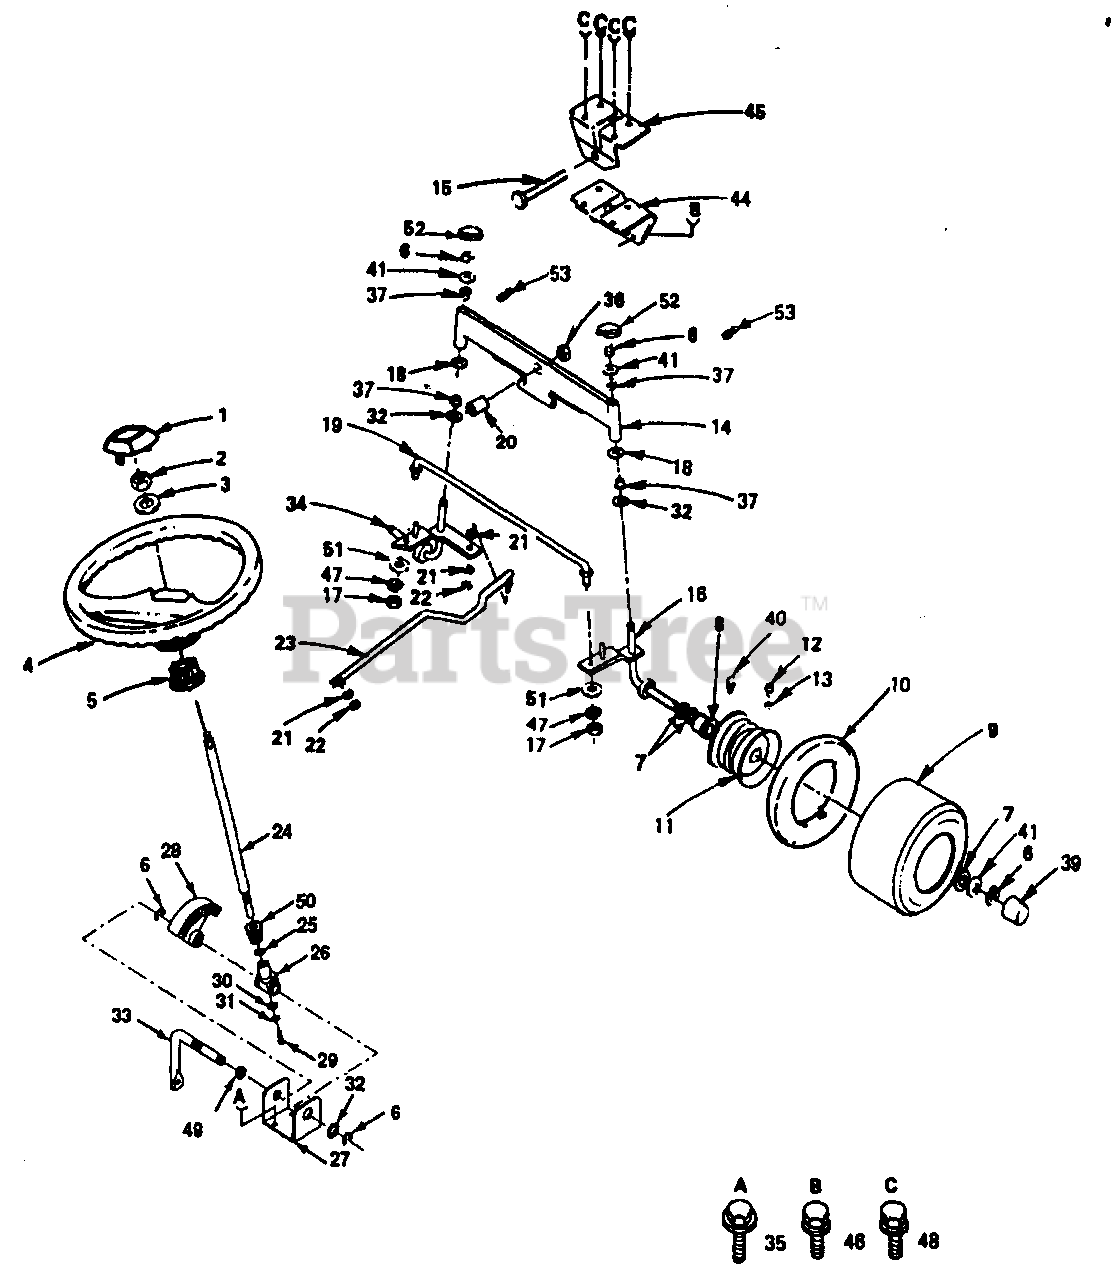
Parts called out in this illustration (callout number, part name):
1	Cap, Steering Wheel
2	Nut, Hex, Toplock Jam 1/2-20
3	Washer 17/32 x 2-1/4 x .160
4	Steering Wheel
5	Adapter, Steering Wheel
7	Washer 25/32 x 1-1/4 x 16 Gauge
8	Wheel Bearings, Front
9	Tire
11	Rim Assembly, Front
14	Axle Assembly, Front
15	Bolt, Hex 5/8-11 x 3-3/4
16	Spindle, Assembly, R.H.
17	Nut, Hex 5/16-24
18	Washer 27/32 x 1-1/4 x 16 Gauge
19	Rod, Tie
20	Spacer, Bearing
21	Washer, Lock 3/8
22	Nut, Hex 3/8-24
23	Link, Drag
24	Shaft Assembly, Steering
26	Support,Shaft
27	Bracket, Steering
28	Gear, Sector
29	Screw, Socket, Hex 1/4 - 20 x 5/8
30	Washer, Shim 1/4 x 5/8 x .062
31	Washer, Lock 1/4
32	Bearing, Thrust
33	Shaft, Pitman
34	Spindle Assembly, L.H.
35	Screw, Hex Washer Head, Thread Forming 3/8-16 x 3/4 Type TT
36	Locknut, Flange 5/8--11
37	Bearing
39	Cover, Wheel, Front
40	Fitting, Grease
41	Washer 25/32 x 1-5/8 x 16 Gauge
44	Support, Saddle, Front
45	Support, Saddle, Rear
46	Screw, Hex Washer Threaded, Roll. 5/16-18 x 1/2
47	Washer, Lock 5/16
48	Screw, Special
49	Nyliner, Snap In
51	Washer 11/32 x 3/4 x 16 Gauge
53	Fltting, Grease
